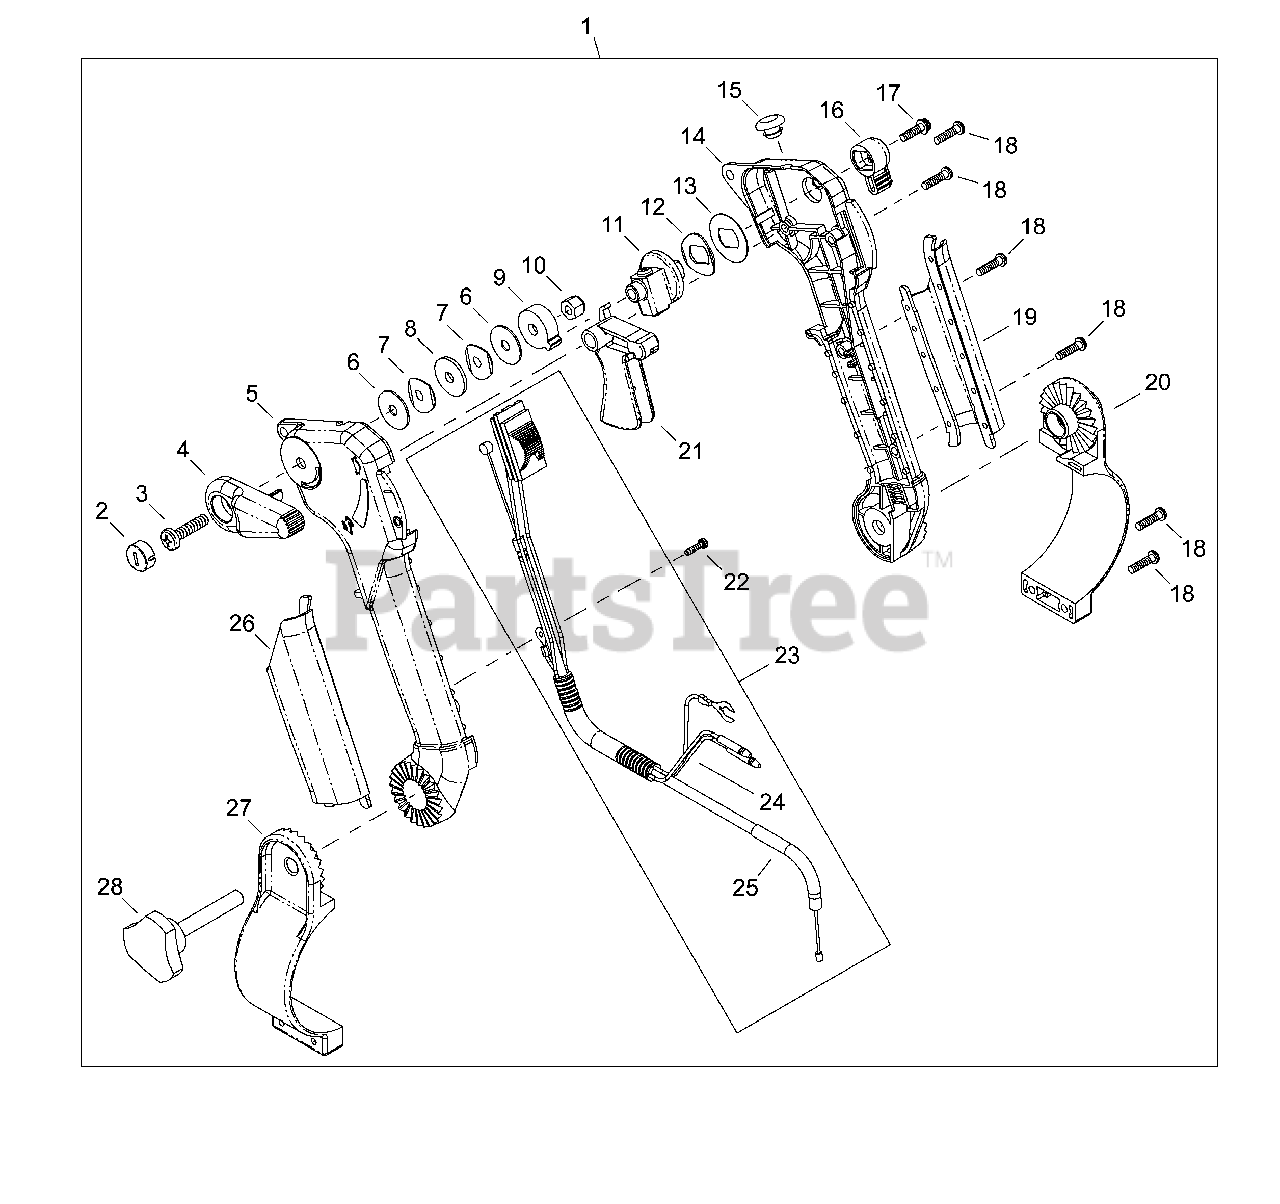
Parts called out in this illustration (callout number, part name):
1	THROTTLE LEVER ASSY
2	CRUISE CONTROL BOLT CAP
3	ADJUSTABLE BOLT
4	LEVER, LOCK
5	HANDLE, CONTROL - LEFT
6	WASHER - 6
7	LOCKWASHER
8	WASHER - 6
9	PLATE
10	NUT - 6 -- NYLON
11	ADJUSTER ASSY
12	WASHER - SPRING
13	WASHER
14	HANDLE, CONTROL - RIGHT
15	PLUG
16	SCREW, METERING LEVER PIN
17	SCREW, METERING LEVER PIN
18	SCREW
19	GRIP - RIGHT
20	BRACKET, HANDLE - RIGHT
21	TRIGGER, THROTTLE
22	SCREW - 3
23	THROTTLE CONTROL ASSY
24	SWITCH, IGNITION
25	CABLE, THROTTLE
26	GRIP - LEFT
27	BRACKET, HANDLE - LEFT
28	KNOB, FASTENER
